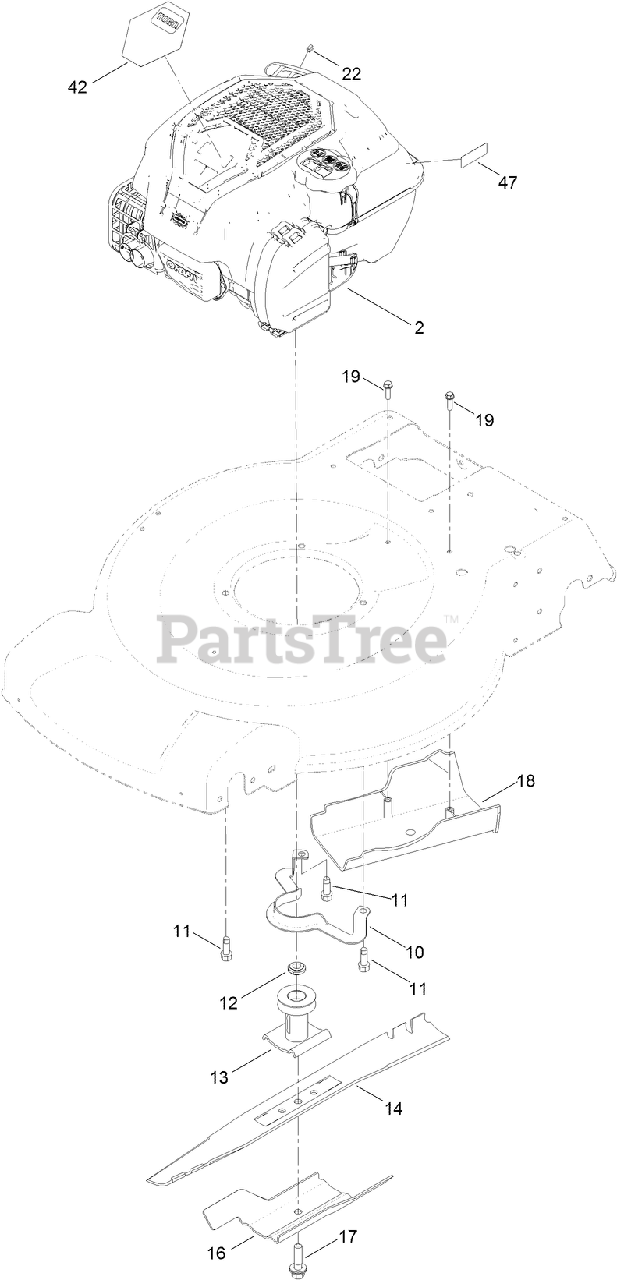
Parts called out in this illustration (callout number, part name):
10	GUIDE-BELT
11	SCREW-TAPTITE
12	SPACER-DRIVER
13	DRIVER-BLADE
16	ACCELERATOR-BLADE
17	BOLT-BLADE
18	COVER-BELT
19	SCREW-HWH
22	STOP-ROPE
42	DECAL-SHROUD
47	DECAL-LEVEL, FUEL
